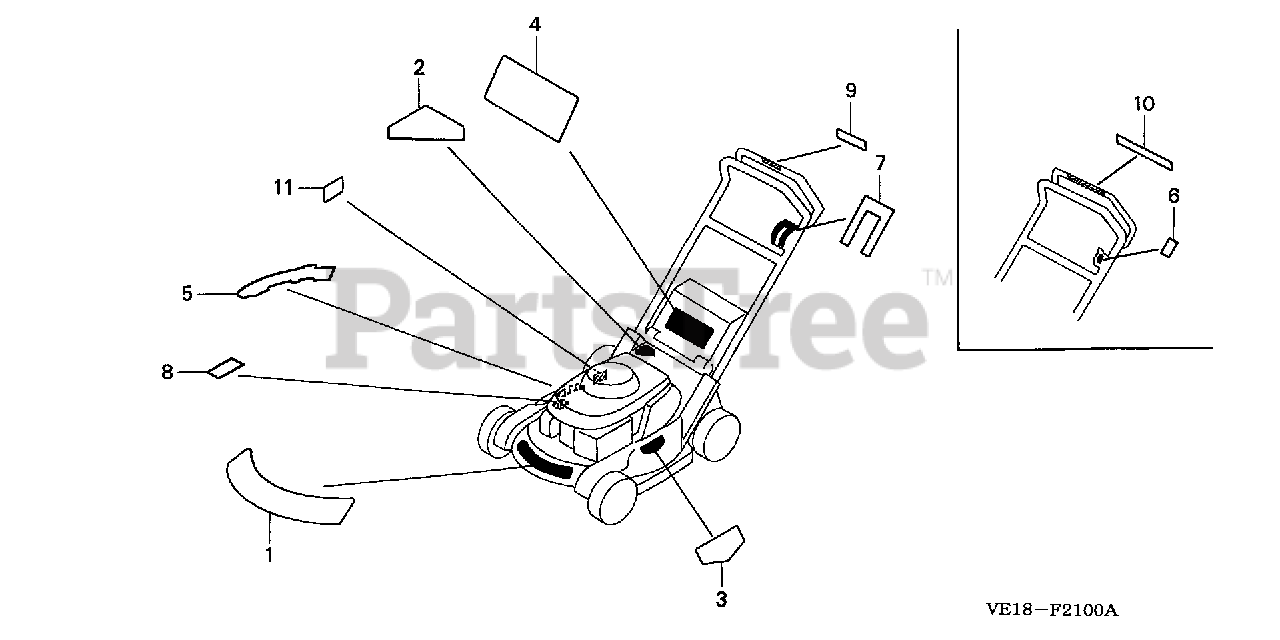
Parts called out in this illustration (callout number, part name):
1	MARK, EMBLEM (HRB215)
2	CAUTION C, HOUSING
3	LABEL, STEP POSITION (ENGLISH)
4	LABEL, WARNING (ENGLISH)
5	MARK (H.S.T.)
7	MARK, THROTTLE INDICATION (ENGLISH)
8	LABEL, HEAT WARNING
9	MARK, BLADE CONTROL (ENGLISH)
11	MARK, OIL CAUTION
